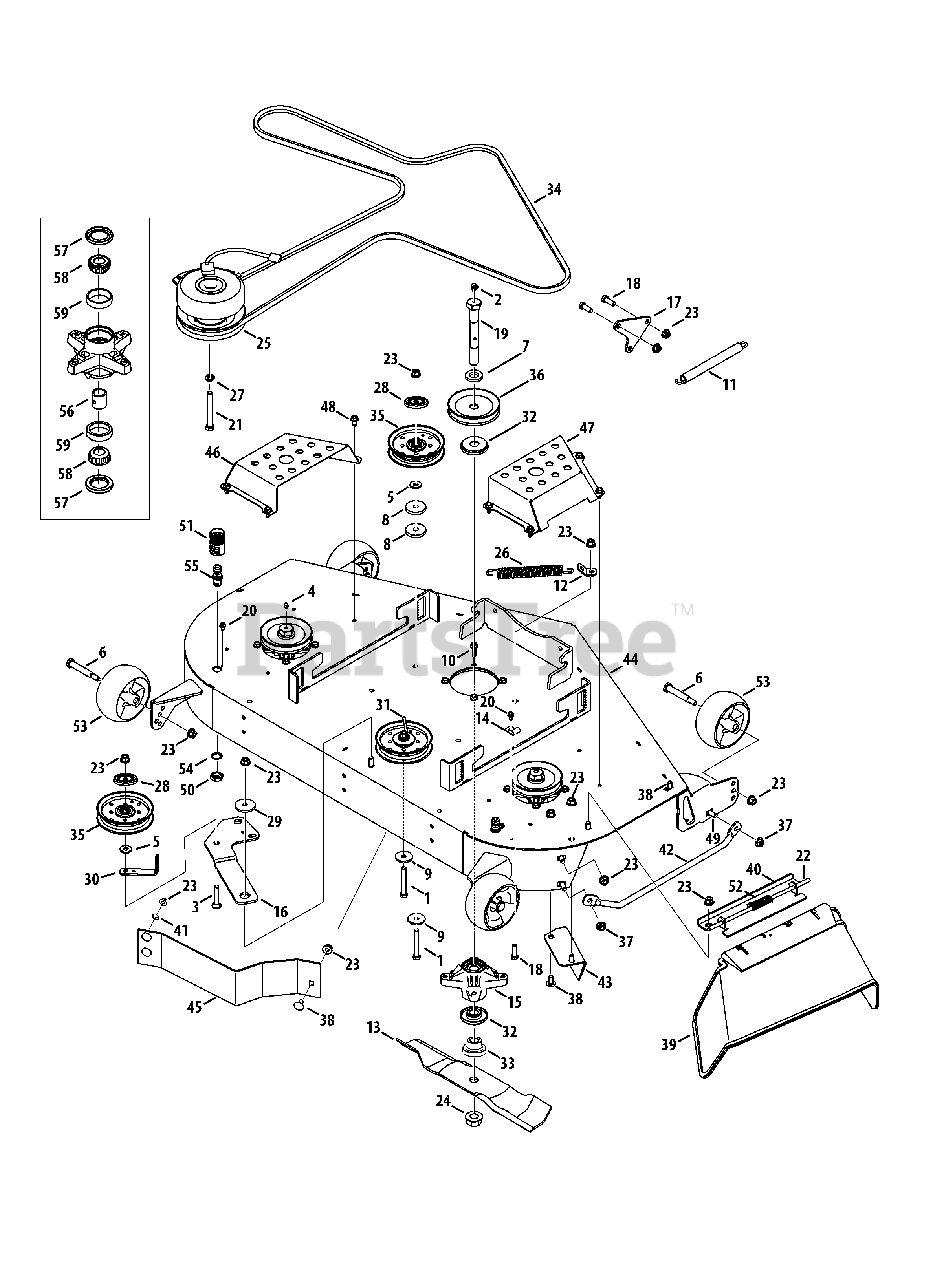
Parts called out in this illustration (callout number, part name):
1	Hex Screw, 3/8-16 x 2.50
2	Grease Fitting, 1/4-28 x .788
3	Carriage Bolt, 3/8-16 x 2.00
4	Straight Grease Fitting, 1/4-28
5	Washer, .406 x 1.00 x .105
6	Shoulder Bolt, 3/8-16 x .496 x 2.50
7	Spacer, .812 x 1.47 x .218
8	Washer, .470 x 1.50 x .225
9	Washer, .390 x 1.50 x .134
10	Flange Hex TT Screw, 5/16-18 x 1.00
11	Hook Ext. Spring, .75 x 7.89 x .14
12	45-Degree Spring Mount Bracket
13	Hi-Lift Blade, 17.0
14	Retainer Hook Bracket
15	Deck Spindle Assembly
16	48" Plate Idler
17	Spring Mount Plate
18	Hex Screw, 3/8-16 x 1.00
19	Hex Screw, 3/4-16 x 6.00
20	Hex Washer TT Screw, 1/4-20 x .500
21	Hex Head Screw, 7/16-20 x 3.25
22	Chute Deflector Rod
23	Flange Lock Nut, 3/8-16
24	Flange Lock Nut, 3/4-16
25	Electric PTO Clutch
26	Extension Spring, .91 x 7.33
27	Lock Washer, 7/16
28	Pulley Cap
29	Shoulder Spacer, .884 x .190
30	Belt Guard Bracket
31	Belt Keeper Rod
32	Deck Spindle Spacer
33	Spindle Spacer, .76 x 2.0 x 1.1
34	Hi-Performance Belt
35	Idler Pulley
36	V-Type Pulley
37	Counterlock Flange Nut, 3/8-16
38	Carriage Bolt, 3/8-16 x .75
39	Fab Deck Deflector Chute
40	Deflector Chute Bracket
41	Push Nut Retainer,
42	Fab Deck Chute Finger Guard
43	Micro Chute Baffle
45	48" Standard Baffle
46	48" LH Belt Cover
47	48" RH Belt Cover
48	Hex Washer Screw, 5/16-18 x .750
49	Carriage Bolt, 3/8-16 x .75
50	Hex Nut, M16-1.5
51	Water Nozzle Adapter
52	Torsion Spring
53	Deck Wheel, 5.0
54	Lock Washer, 17 x 23.8 x 1.95
55	Water Deck Nozzle
56	Bearing Spacer
58	Cone Bearing, .750"
59	Bearing Cup, .750"
